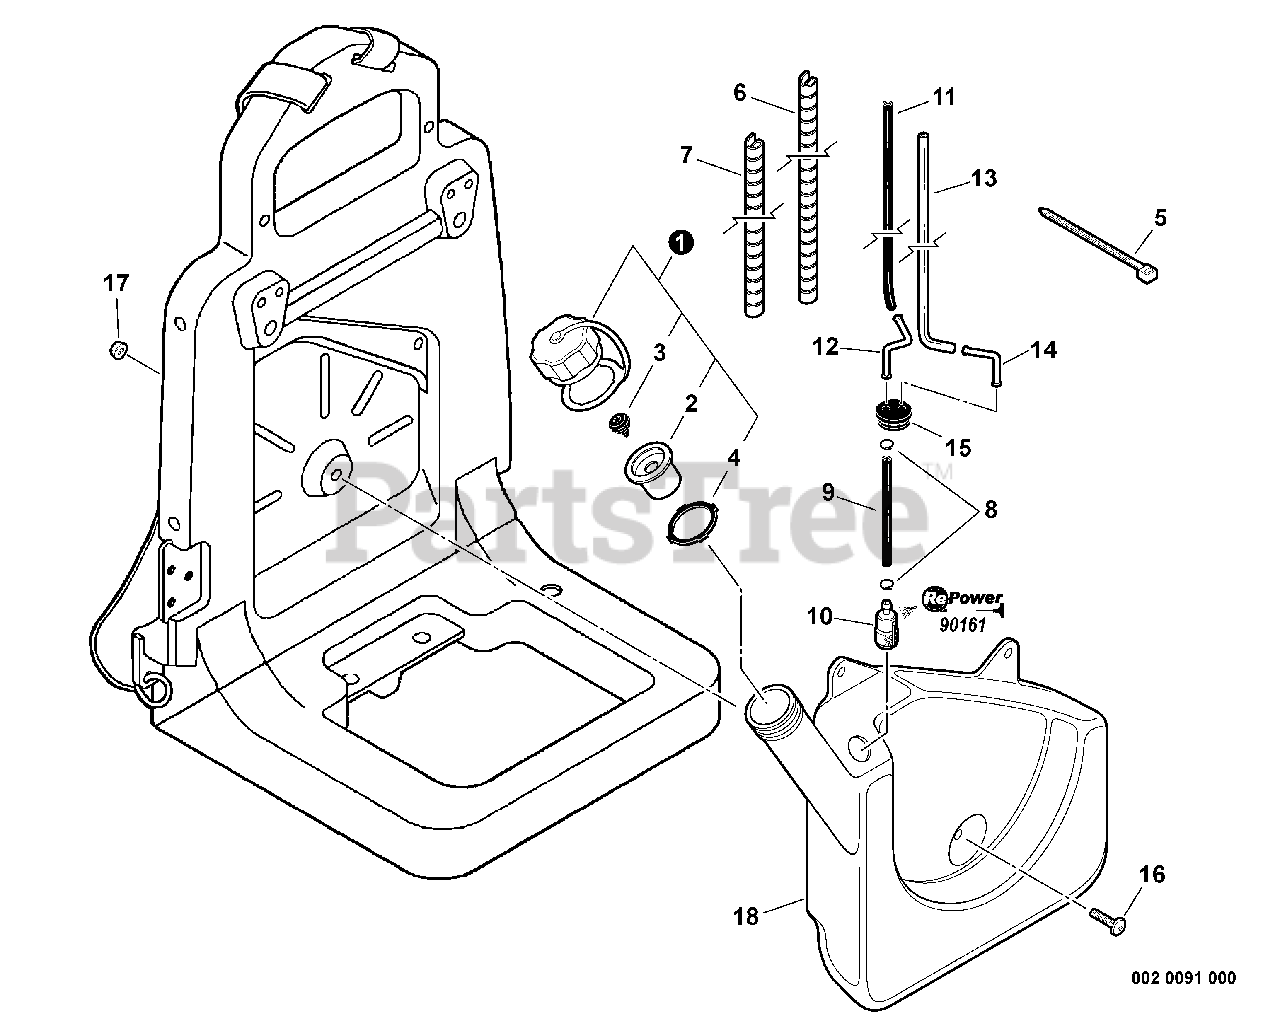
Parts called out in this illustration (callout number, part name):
1	CAP ASSY, FUEL
2	HOLDER, VENT
3	VENT ASSY
4	GASKET, FUEL CAP
5	STRAP, TIE
7	WRAP, SPIRAL
8	CLIP Ø6.5 MM
9	PIPE, FUEL 3×6×280 MM
10	FILTER, FUEL
11	PIPE, FUEL
12	CONNECTOR, PIPE
13	PIPE, FUEL
14	CONNECTOR, PIPE
15	GROMMET
16	SCREW 5×20
17	NUT, FLANGE M5
18	TANK, FUEL
19	TUNE-UP KIT - REPOWER
